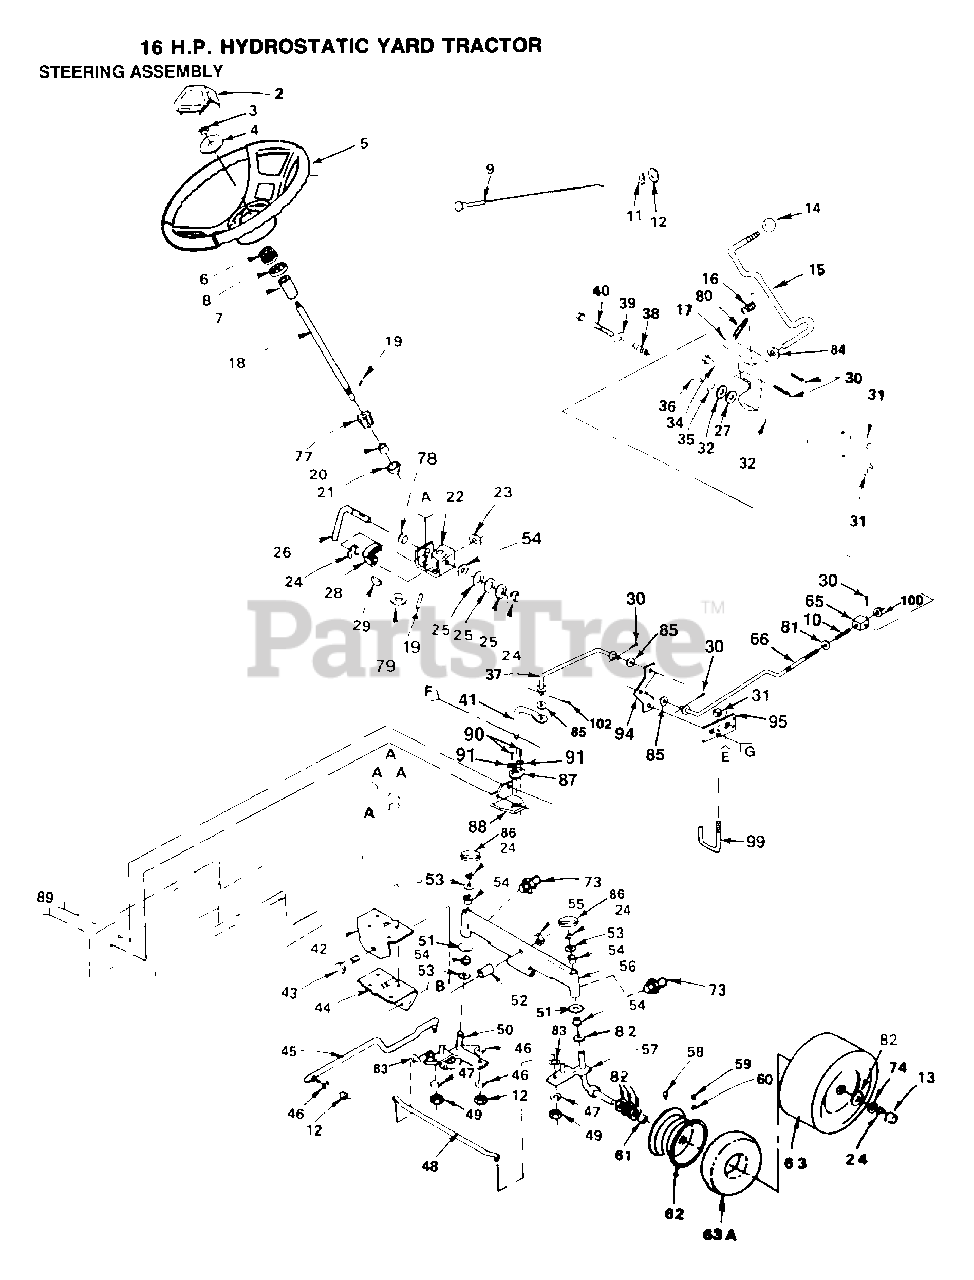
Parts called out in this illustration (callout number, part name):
1	DECAL, STEERING WHEEL INSERT
2	INSERT-WHEEL LT
6	ADAPTER LT
10	SPRING GTV
11	LOCKWASHER
13	HUB CAP
14	KNOB.DUCKHEAD.1/2
15	ROD.YTH
16	SPRING TORSION
17	BRKT CONTROL HYT
18	STEERING SHAFT T
20	SHAFT SPACER LT
21	BUSHING
23	WASHER D
24	RING
25	WASHER .T
26	ROD STEERING T
27	WASHER HYT
28	GEAR.SECTOR.HYT
29	KEY-WOODRUFF LT
30	COTTER PIN
32	WASHER FRIC HYT
33	WASHER
34	BOLT HYT
35	WASHER D
36	SPACER HYT
37	LINK CONTROL
38	SPRING HYT
39	WASHER
40	BOLT - HEX 3/8 - 16 X 3
41	ARM ASM PUMP
42	SUPPORT-SADDL T
43	BOLT LT
44	SUPPORT.SADDLE.FT
45	LINK-DRAG LT
46	LOCKWASHER
47	LOCKWASHER
48	ROD TIE
49	NUT.LOCK.5/16-24
50	SPINDLE-LH LT
51	WASHER
52	BEARING
53	WASHER .T
54	COL. SRTG. BEAR.
55	"NUT-LOC,FLANGE LT"
56	FRONT AXLE
58	FITTING LT
59	VALVE STEM LT
60	VALVE CAP
61	"FLANGE, BEARING"
63A	TUBE.5.3/4.5/6
65	TRUNION HYT
66	ROD ADJ CONTROL
71	SCREW LT
73	ZERK M
74	WASHER
77	GEAR PINION T
78	NYLINER T
80	SPRING.RETAINER
81	WASHER T
82	WASHER
83	WASHER M
84	WASHER
85	WASHER T
86	CAP
87	GUIDE CONTROL
88	BRKT
89	SCREW
90	SCREW
91	WASHER
92	SCREW.HXHD.10-2
94	BELLCRANK
95	BRKT BELLCRANK
99	KEEPER
100	NUT
101	SHOULDER BOLT LT
102	RETAINER M
